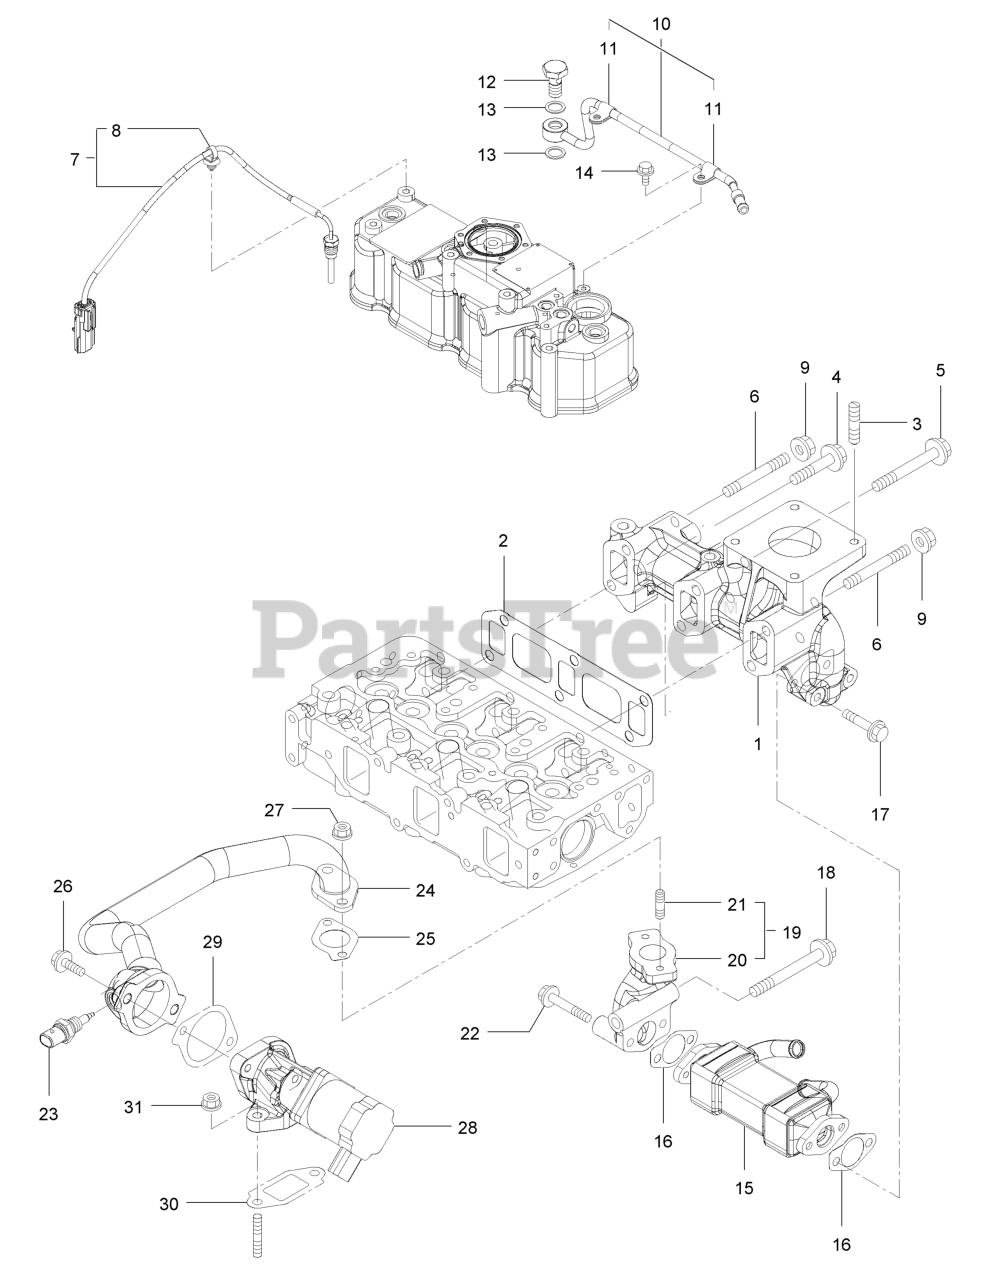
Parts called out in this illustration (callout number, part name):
1	Manifold-Exhaust
2	Gasket-Manifold, Exhaust
7	Sensor-Temp, Exhaust
8	Band-Clip
10	Exhaust Pipe ASM
12	Bolt-Joint, Pipe
15	Cooler-E G R
16	Gasket-Cooler, E G R
19	E G R Pipe ASM
20	Pipe-Out, E G R
23	Sensor-Gas Temp, E G R
24	E G R Pipe ASM
28	Valve-E G R
29	Gasket-Intake Valve, E G R
30	Gasket-Out Valve, E G R
